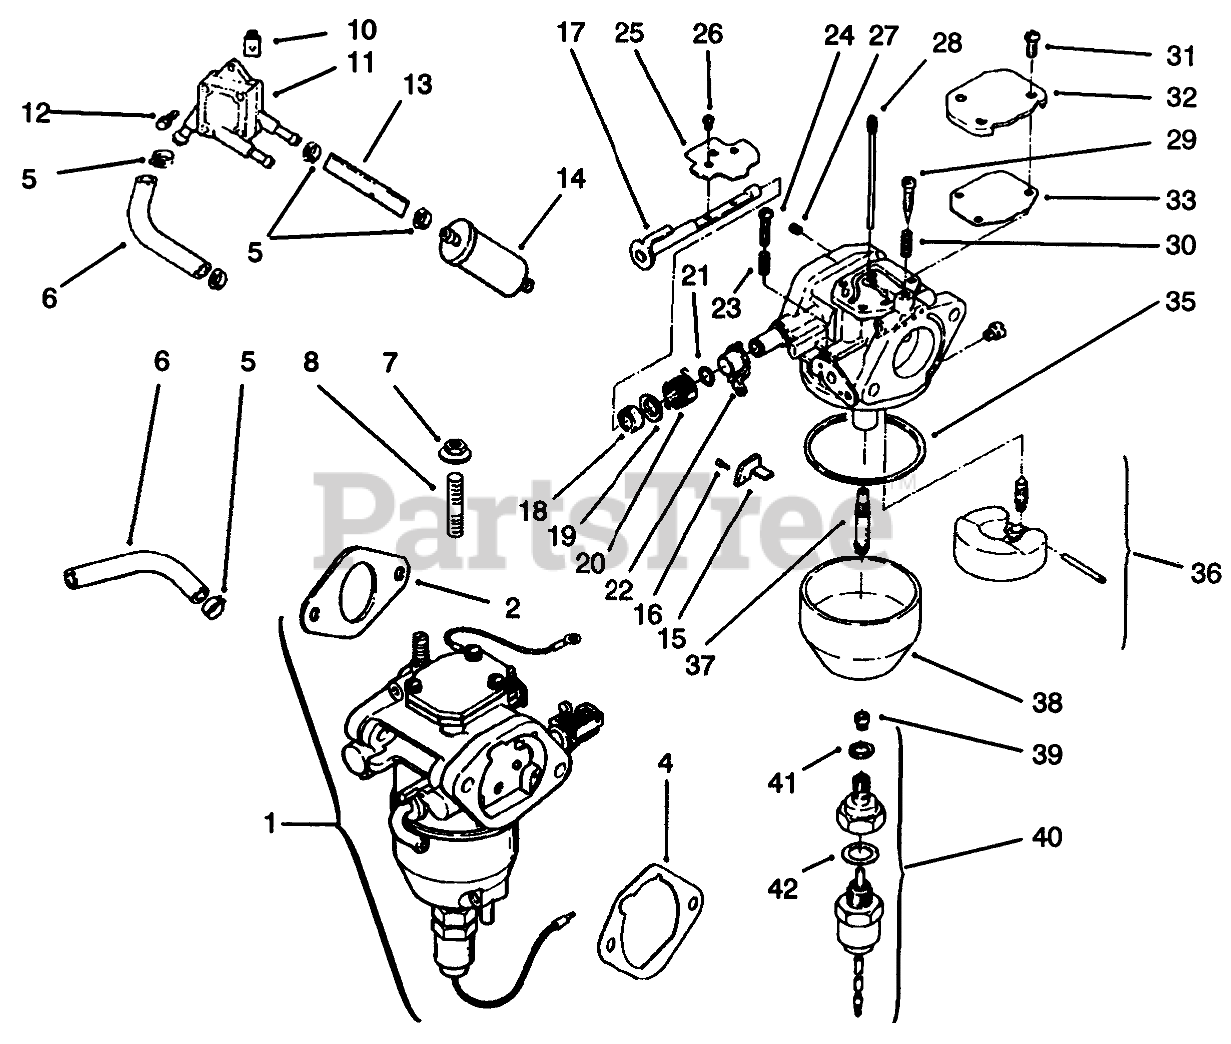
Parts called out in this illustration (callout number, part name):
2	Gasket-Carburetor
4	Gasket-A/C Base
5	Clamp
6	Line-Fuel 10 1/2"
11	Pump-Fuel
13	Line-Fuel 3 1/2"
14	Filter-Fuel
15	Bracket-Throttle Stop
16	Screw
17	Shaft-Choke
18	Washer
19	Collar-Choke
20	Spring-Choke Return
21	Ring-Choke Lever
22	Lever-Choke
23	Spring-Throttle Screw
24	Screw-Throttle Adjust
25	Valve-Choke
26	Screw-Throttle Shaft
27	Jet-Air Bleed
28	Jet-Slow
29	Screw-Idle Adjust
30	Spring-Idle Adjust Screw
31	Screw
32	Cover-Passage
33	Gasket-Passage Cover
35	Gasket-Float Chamber
36	Kit-Float Repair
37	Nozzle-Main
38	Chamber-Float
39	Jet-Main
40	Kit-Solenoid INC 41-42
41	Gasket-Chamber Screw
42	Gasket-Solenoid
